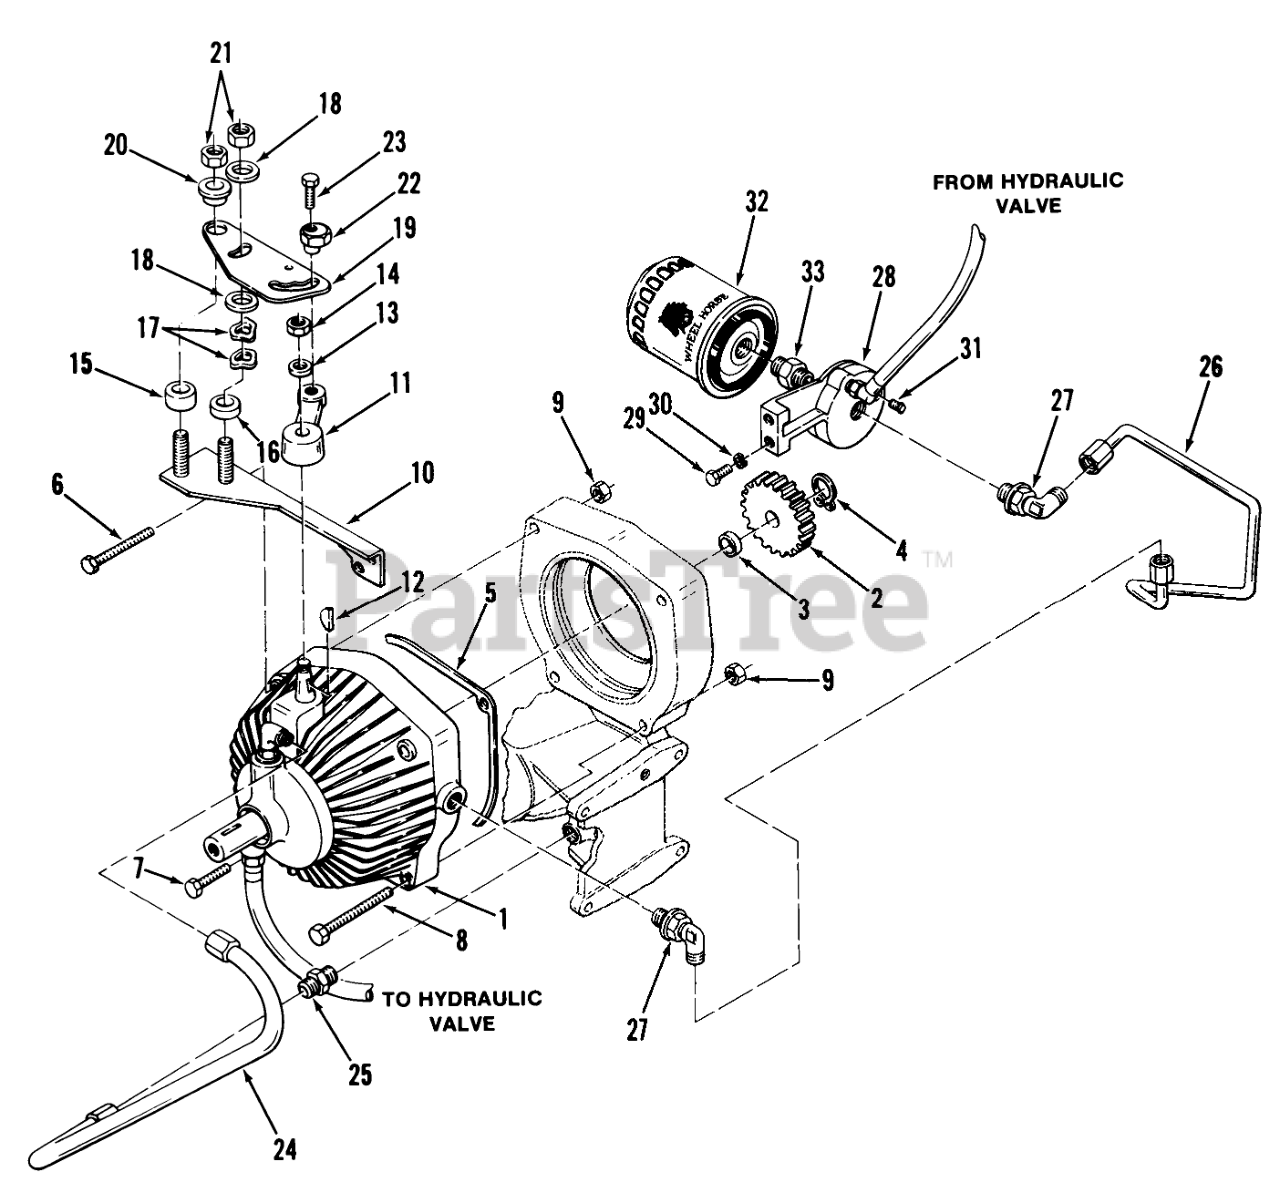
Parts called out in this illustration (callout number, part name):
1	Pump & Motor
2	GEAR 22T DRIVE
3	SPACER GEAR
4	SNAP RING- 5/8 EXT
5	GASKET
6	H H C S
7	Bolt
8	Bolt 3/8-16 x 6 1/2
9	Nut
10	ASSY-PLATE B
11	ARM-SPEED CONTROLB
12	Key #5 Woodruff
13	Washer
14	Eslok Nut
15	SPACER-PIVOT
16	SPACER-FRICTION
17	WASHER-SPRING DISC
18	FRICTION WASHER
19	CAM-SPEED CONTROL (NS)
20	CAM-SPACER
21	Nut Conlok 3/8-16
23	Bolt
24	ASSY-TUBE-SUCTION
25	FITTING-TUBE
26	ASSY-TUBE-FILTER
27	ELBOW
28	BASE-FILTER
29	Bolt
30	Lockwasher
31	PLUG 1/4 PIPE ALLEN
32	Filter-Oil
33	FITTING
